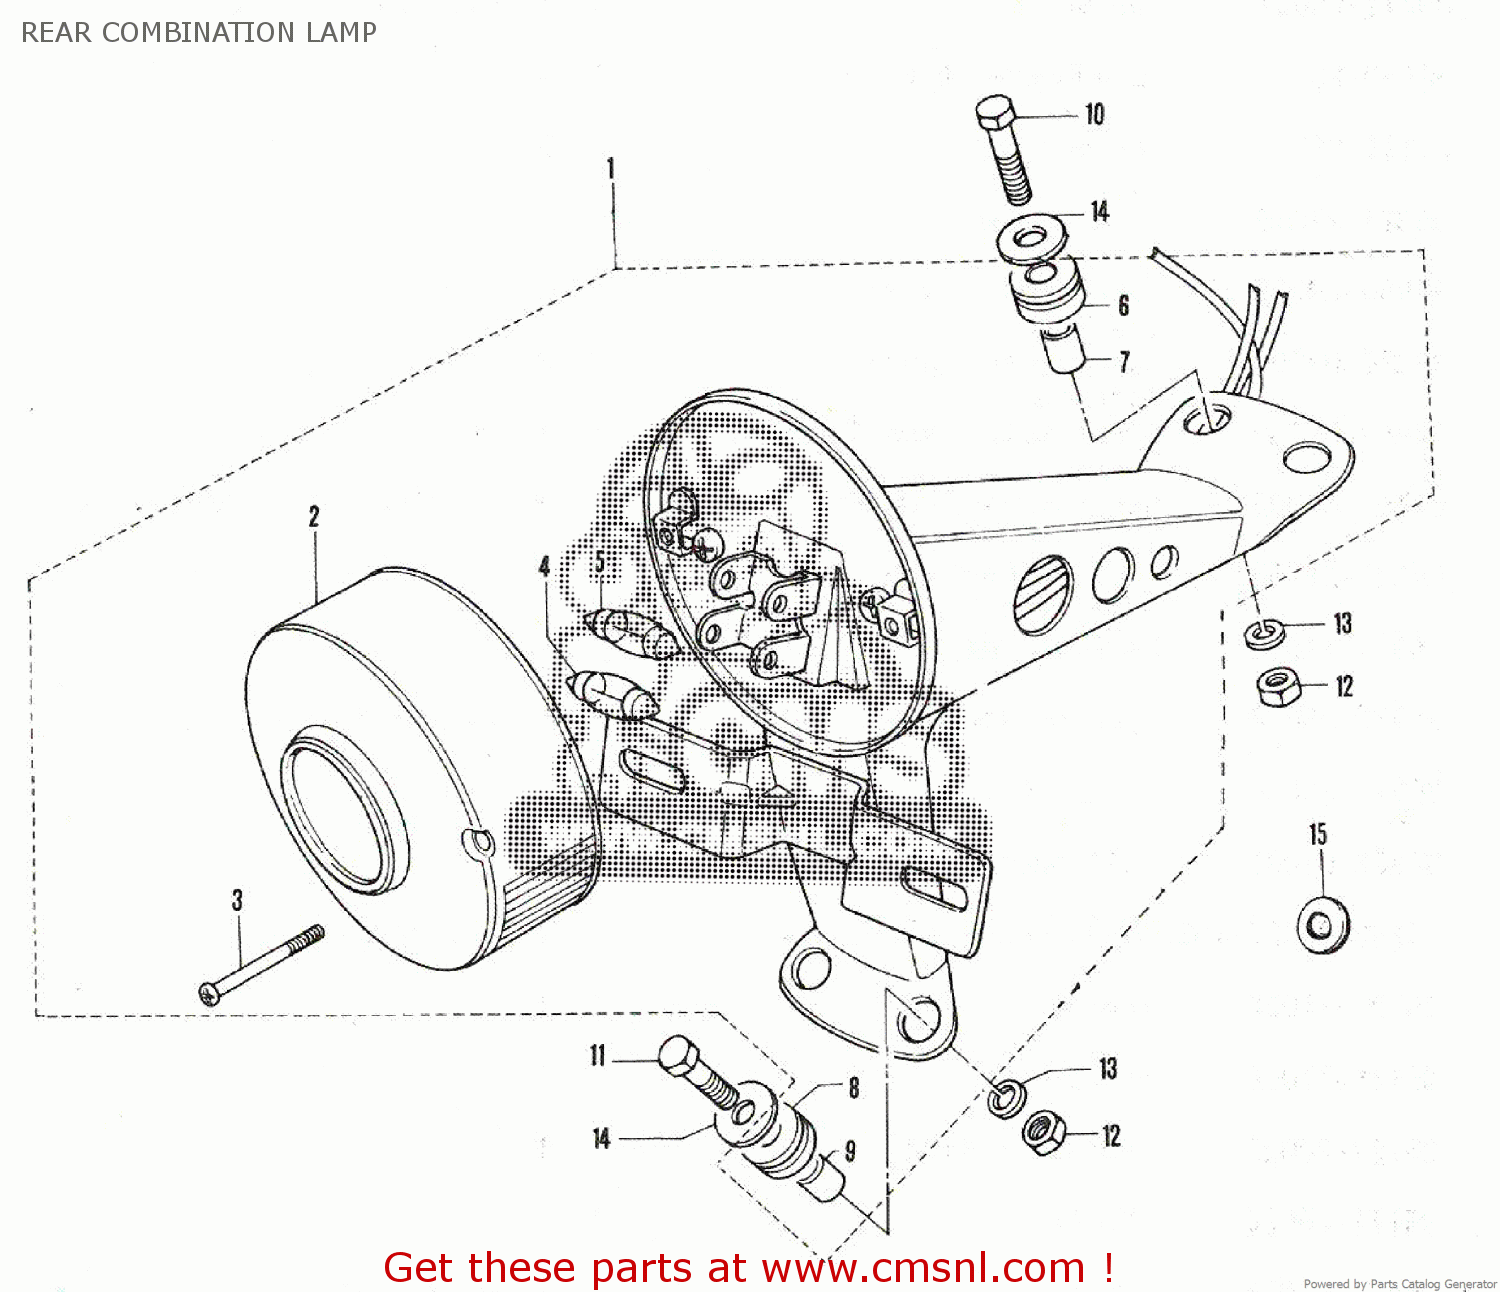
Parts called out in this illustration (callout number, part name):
1	REAR COMBINATION LAMP ASS'Y
2	LENS,REAR COMBI
3	CROSS HEAD SCREW
4	BULB
5	BULB
6	CUSHION
7	SPACER,REAR COMBINATION LAMP
8	CUSHION
9	SPACER,REAR COMBINATION LAMP
10	BOLT
11	BOLT
12	NUT
13	LOCK WASHER
14	WASHER
15	GROMMET
